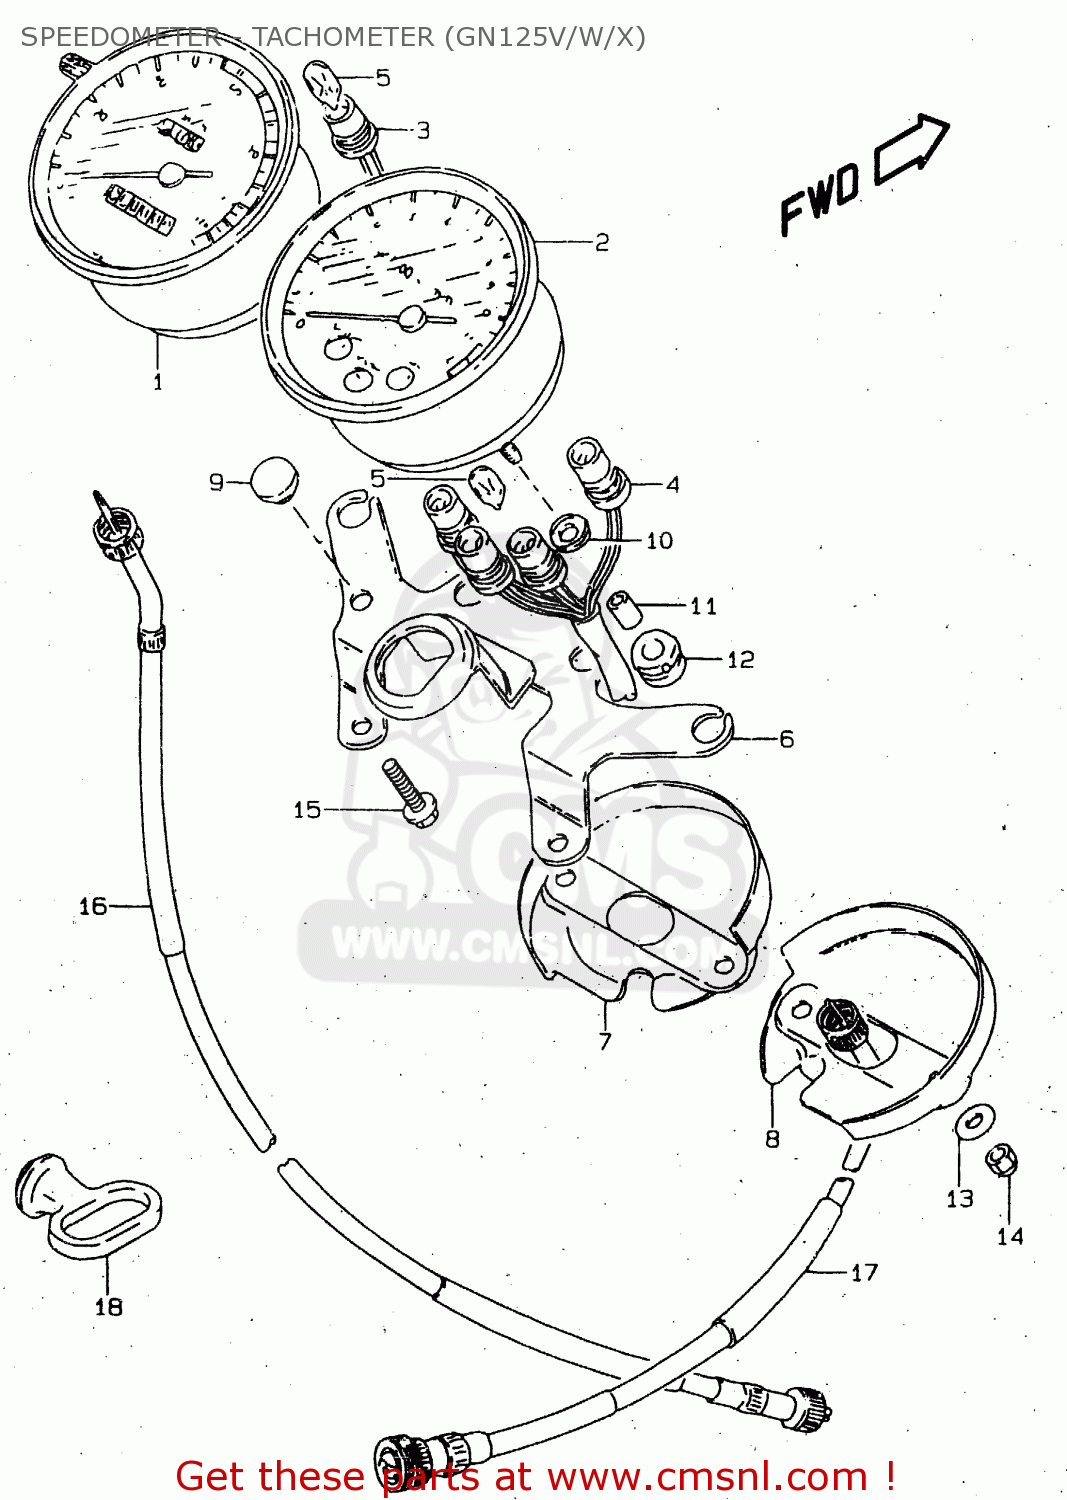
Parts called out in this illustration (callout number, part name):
1	SPEEDOMETER(KILO)
2	TACHOMETER
3	SOCKET,SPEEDOMETER
4	SOCKET,TACHOMETER
5	BULB(12V3.4W,T10,BF175-01450A)
6	BRACKET,METER
7	UNDER COVER,SPEEDOMETER
8	UNDER COVER,TACHOMETER
9	CUSHION,METER
10	WASHER(5.2X16X1)
11	SPACER,SPEEDOMETER
12	CUSHION,METER
13	WASHER(5.5X16X1.5)
14	NUT
15	BOLT
16	CABLE ASSY,SPEEDOMETER
17	CABLE ASSY,TACHOMETER
18	GUIDE,CABLE
